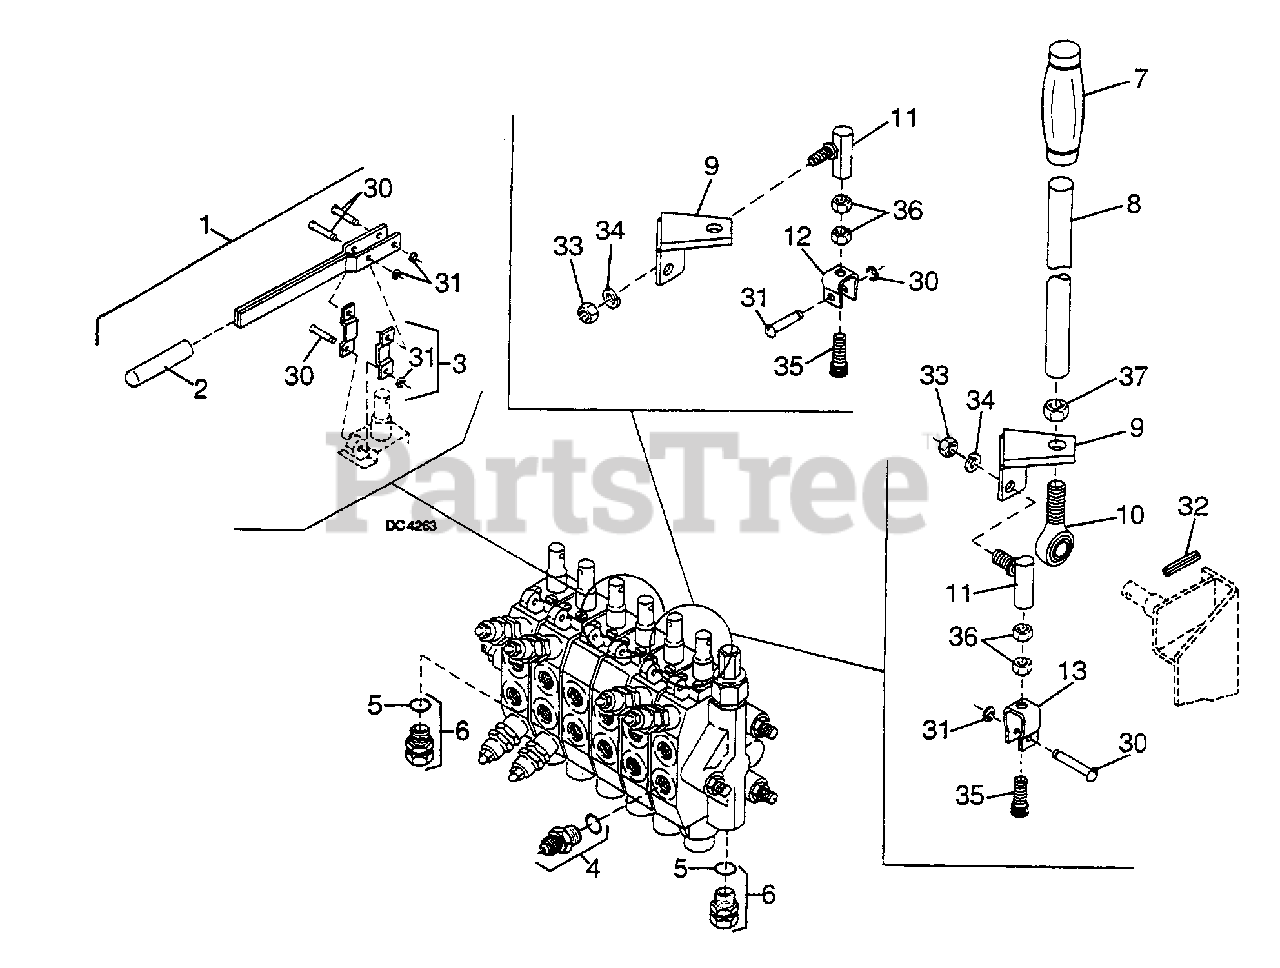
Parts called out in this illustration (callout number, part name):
1	Stabilizer handle assembly
2	Rubber handle
3	Stabilizer handle link kit
4	9/16 - 18 to O-Ring connector
5	#906 O-Ring, .468 ID x .078 cross section
6	9/16 - 18 x 3/8 NPT Union
7	Grip, .63 x 1.06 x 5.0 Black
8	Control handle
9	Handle arm weldment assembly
10	Rod end 7/16 NF male
11	Ball joint, 5/16 NF
12	Clevis - Valve spool .69
13	Clevis - Valve spool. 1.00
30	Valve linkage pin
31	.025 x .156 External E-ring
32	3/16 x 1-1/8 Spring pin
33	5/16 NF Hex nut
34	5/16 Standard lockwasher
35	5/16 NF x 1 Socket head cap screw
36	5/16 NF Hex jam nut
37	7/16 NF Hex nut
